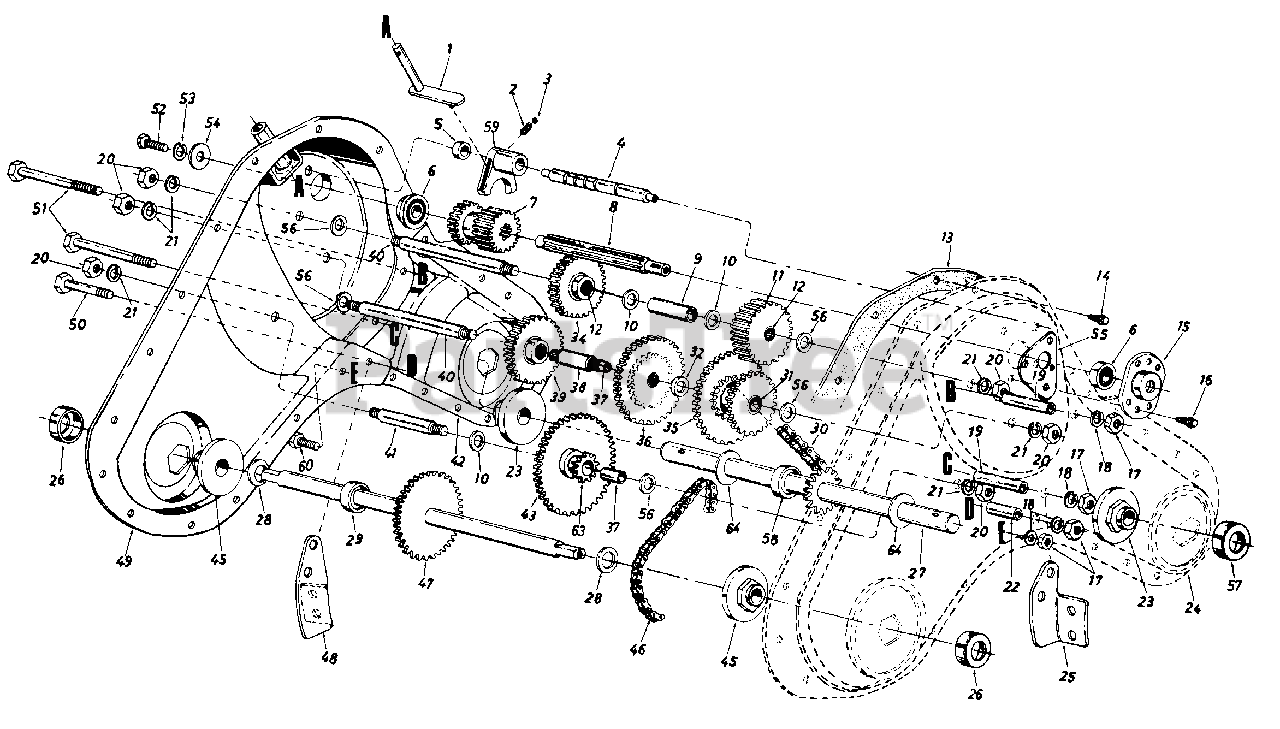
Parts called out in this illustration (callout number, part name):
1	Shifting Bracket Ass'y.
2	Compression Spring .50" Lg.
3	Ball Detent .250n Dia.
4	Detent Shaft 1/2" Dia.
5	Spacer .505" I.D. x .88" O.D.
6	Ball Brg. .62" l.D. x 1.38"
7	Spur Gear 1 6T (Input)
8	Input Spline Shaft 7/8"
9	Spacer .657" I.D. x 2.85n Lg.
10	Fl-Wash. .640" I.D. x 1.24"
11	Spur Gear 30T 7/8" I.D.
12	Needle Bearing 5/8" l.D.
13	Gasket-Trans. Hsg.
14	Hex Wash. S-Tap Scr. 1/4-20 0 x 60" Lg
15	1-3/8" Dia. Bearing Housing
16	Hex TT-Tap Scr. 1/4-20 x .75"
17	Hex Nut 5/16-18 Thd .
18	L-Wash. 5/16n l.D.
19	Spacer 1.56n Lg.
20	Hex Nut 7/16-20 Thd.
21	Bell-Wash. .45" l.D. x 1.0"
22	Spacer 1.015" Lg.
23	Tine Shaft Brg. 1.002 x 2.50
24	Trans. Housing Ass'y.-L.H.
27	Tine Shaft Ass'y. 1" O.D.
28	Fl-Wash. .75n l.D. x 1.5" O.D.
29	Spacer .75n l.D. x .50" Lg.
30	Chain #50 5/8 Pitch x 52 0 Links-Endless
31	Needle Bearing 5/8" l.D.
32	Fl-Wash. 5/8n l.D.
34	Spur Gear 30T 12/16" I.D.
35	30/44T Gear Ass'y. Comp.
36	Spur Gear 44T
37	Sleeve Bearing
38	Gear Hub 3/4" I.D. x 3" Lg.
39	Spur Gear 30T 1.0" I.D. x 1/2" W
40	Jack Shaft 5/8" Dia. x 5"
41	Jack Shaft 5/8" Dia. x 2.38"
42	Trans. Housing Ass'y.-R.H.
43	Spur Gear 55T
45	Wheel Brg. 752" x 2.5'1
46	#420 Chain 1/2 Pitch x 50 0 Links-Endless
47	Wheel Shaft Ass'y. 15.6"
51	Hex Bolt 5/16-18 x 2.5"
52	Hex Bolt 1/4-20 x .62" Lg.
53	L-Wash. 3/8" l.D.
54	Fl-Wash. 1/4" I.D. x .93" O.D.
55	Gear Positioner Bracket
56	Fl-Wash. 7/16" I.D. x 1-3/8"
57	Dust Cover Ass'y. 1" Shaft
58	Spacer 1" l.D. x 2" O.D.
59	Shifting Fork
60	Hex Bolt 5/16-18 x .75" Lg.
63	1 OT Sprocket Ass'y.
64	Thrust Wash. 1.03" I.D. x 1.62" O.D.
